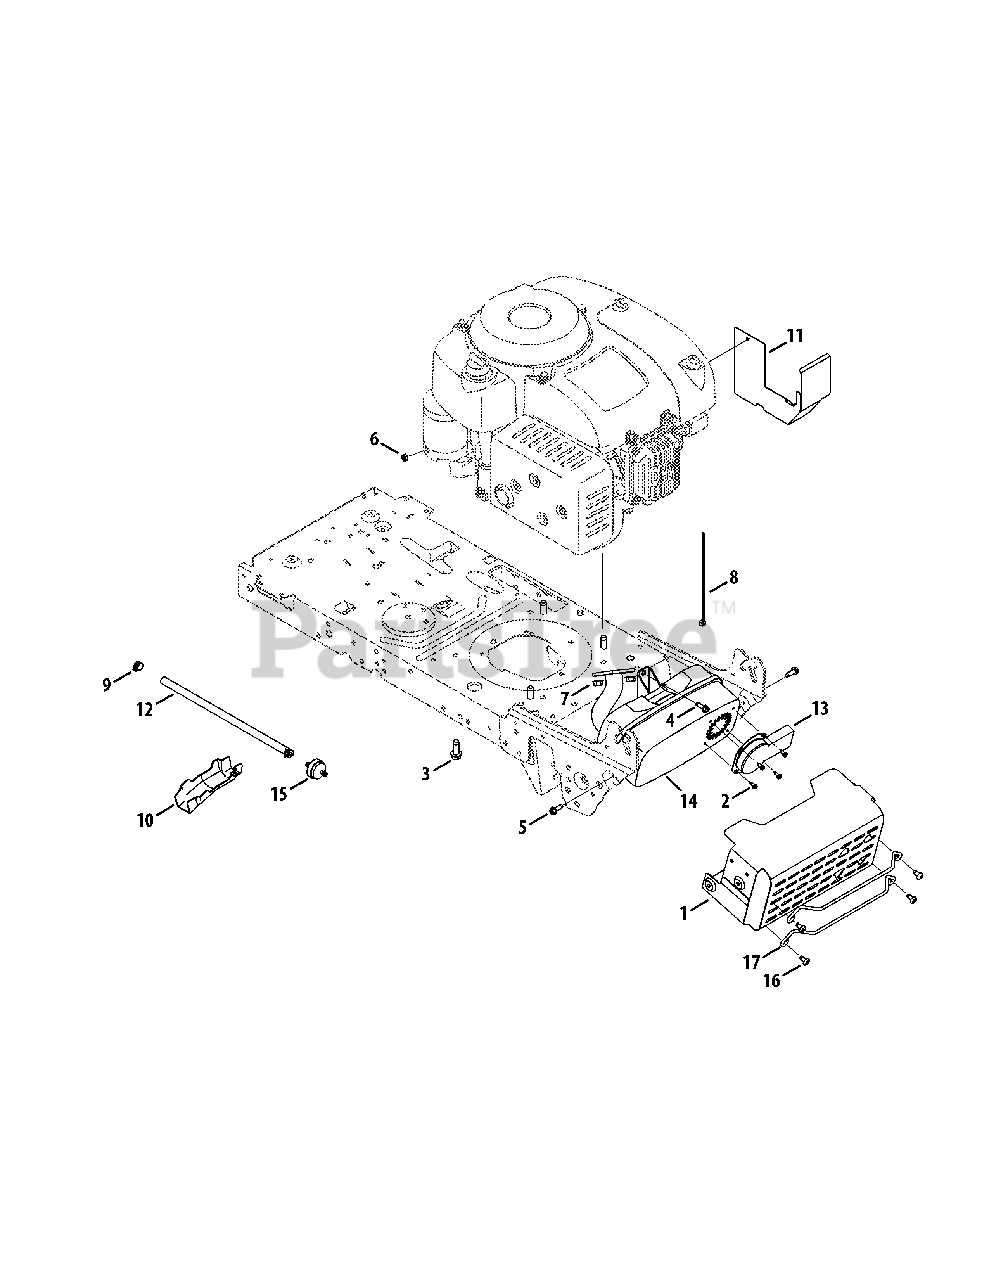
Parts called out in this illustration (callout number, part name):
1	Muffler Shield Assembly
2	Screw, 8-18 x .500
3	Screw, 3/8-16 x 1.0
4	Screw, 1/4-20 x .500
5	Screw, 1/4-20 x .750
6	Nut, M6-1, Hexlock
7	Flange Nut, M8-1.25
8	Cable Tie
9	Clamp Hose, .490 diameter
10	Oil Drain Sleeve
11	Deflector Bracket
12	Fuel Hose, Low Permeation
13	Muffler Deflector Long
14	Muffler
15	Fuel Filter
16	Pan Torx Screw 1/4
17	Muffler Guard Rod
